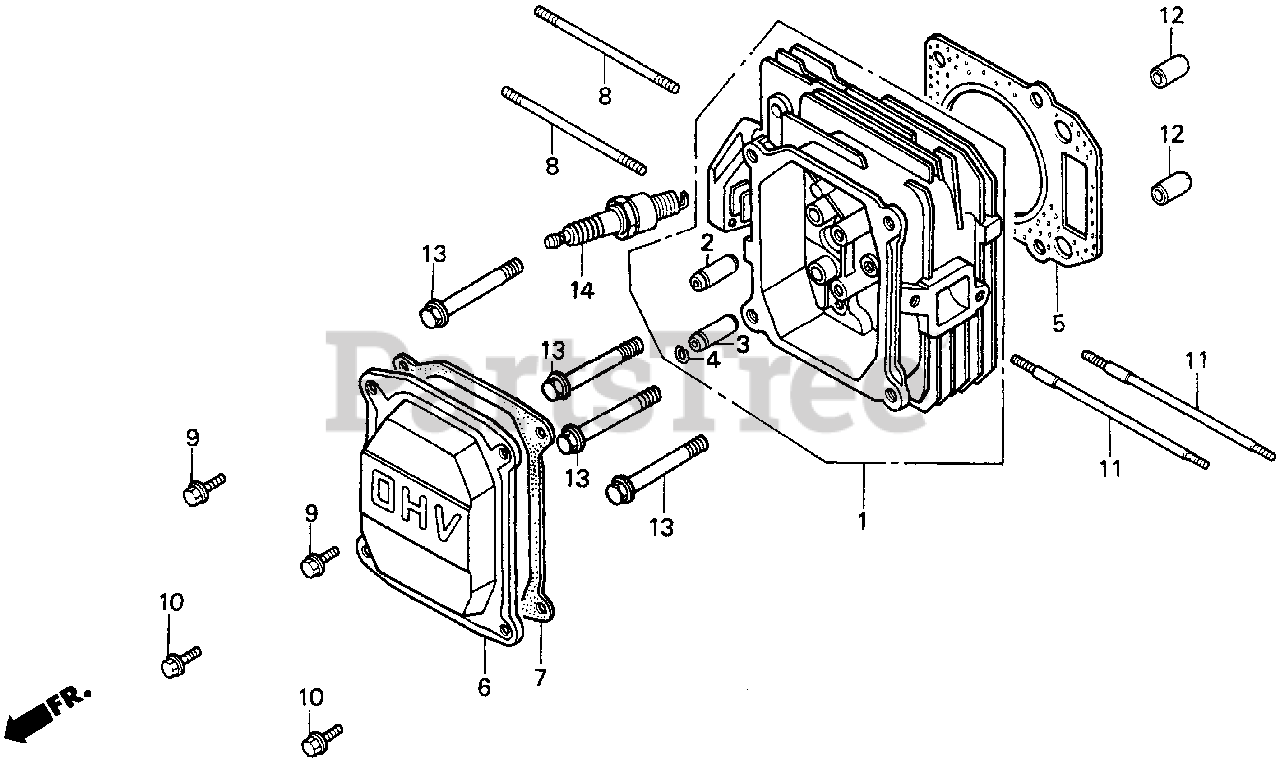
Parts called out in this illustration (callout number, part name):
1	CYLINDER HEAD
2	GUIDE, VALVE (OVER SIZE) Use up to Engine SN 2416541.
2	GUIDE, VALVE (OVER SIZE) Use from Engine SN 6324986.
3	GUIDE, EX. VALVE (OS)
4	CLIP, VALVE GUIDE Use from Engine SN 1231803.
5	GASKET, CYLINDER HEAD
6	COVER, HEAD
7	GASKET, CYLINDER HEAD COVER
8	BOLT, STUD (6X82)
9	BOLT, FLANGE (6X14)
10	BOLT, FLANGE (6X13)
11	BOLT, STUD (6X109)
12	PIN A, DOWEL (10X16)
13	BOLT, FLANGE (8X50)
14	SPARK PLUG (BPR4ES) (NGK)
14	SPARK PLUG (W14EPR-U) (DENSO)
14	SPARK PLUG (BP5ES) (NGK)
14	SPARK PLUG (W16EP-U) (DENSO)
14	SPARK PLUG (BP6ES) (NGK)
14	SPARK PLUG (W20EP-U) (DENSO)
